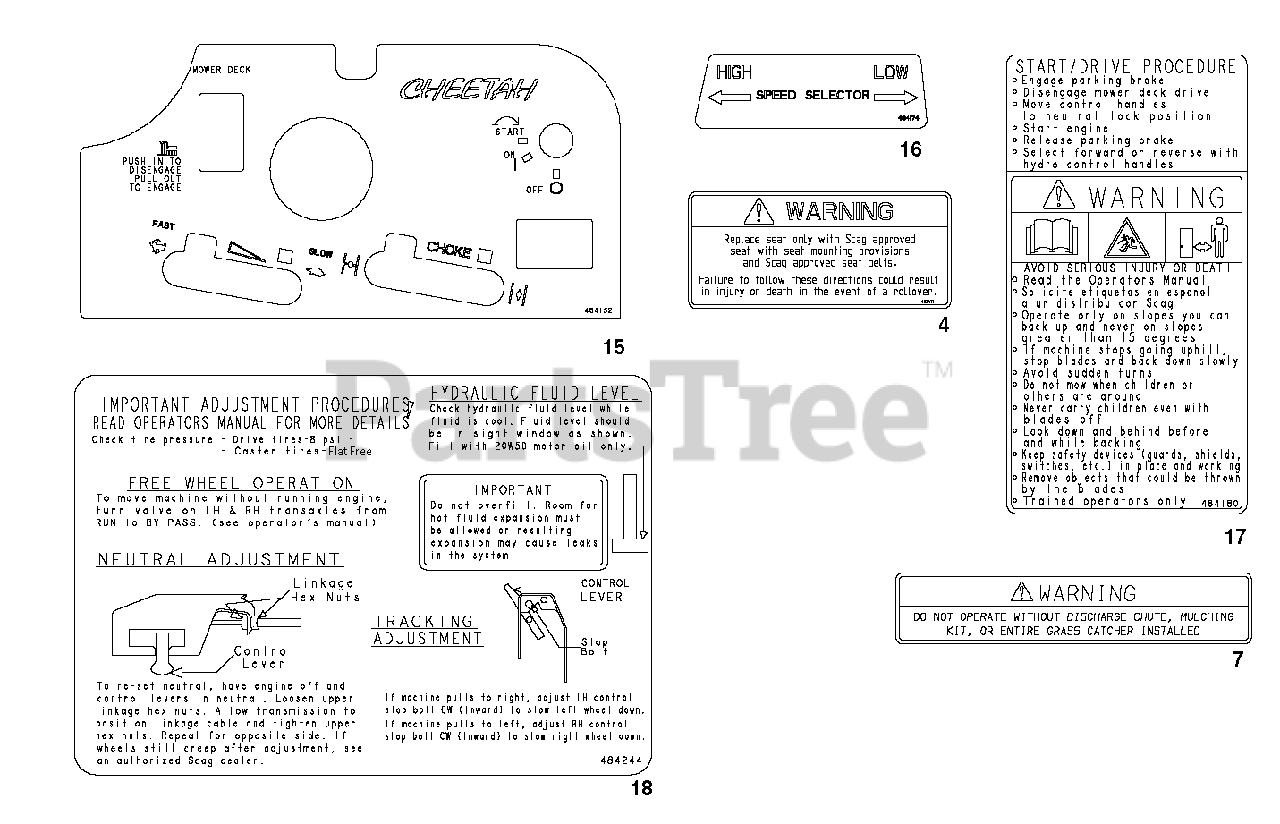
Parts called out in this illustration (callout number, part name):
4	Decal, Seat Replacement
7	Decal, Warning
15	Decal, Instrument Panel - SCZ
15	Decal, Instrument Panel - SCZ - EFI
16	Decal, Speed Control
17	Decal, Start / Drive
18	Decal, Adjustments - SCZ
